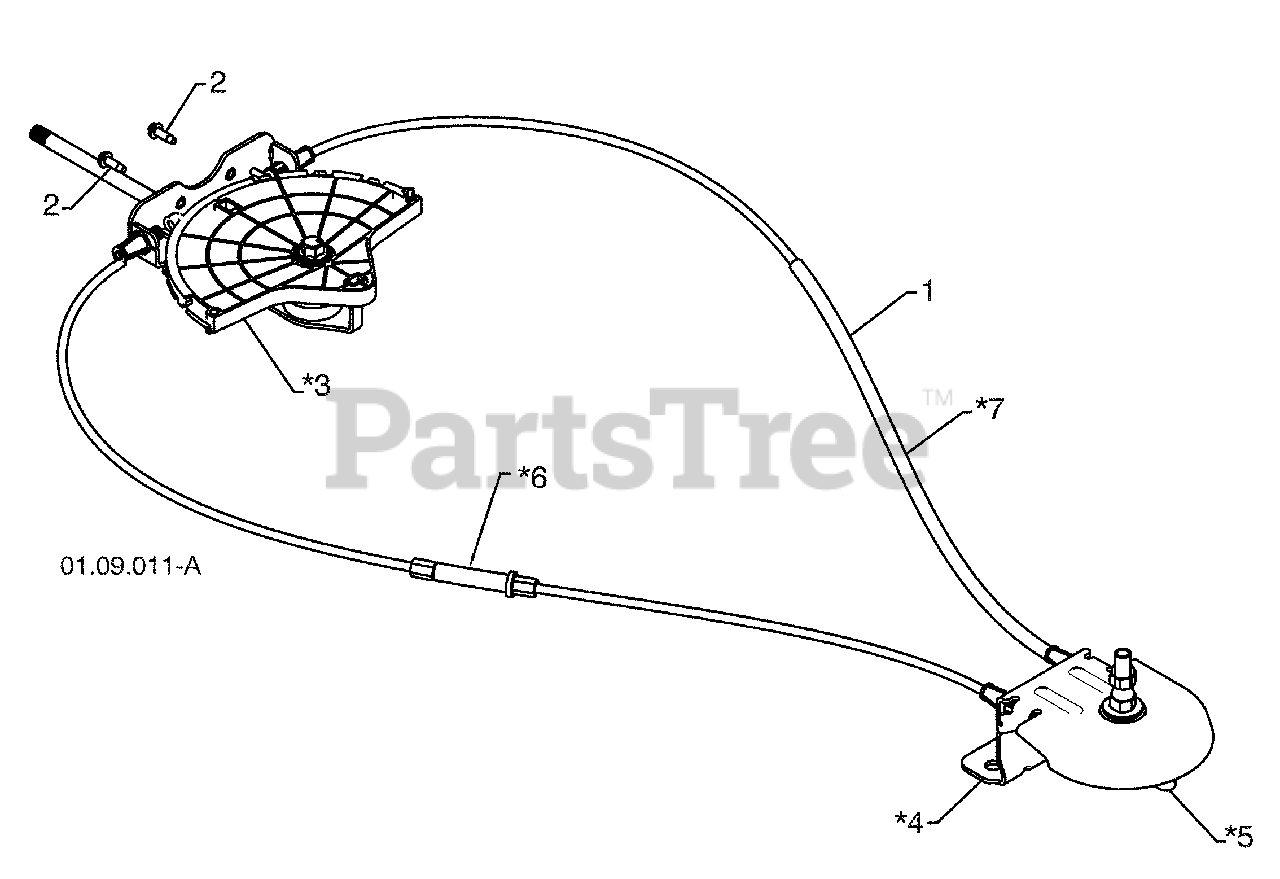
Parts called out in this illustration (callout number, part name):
1	LEVER/CABLE ROTATOR ASSEMBLY
2	SCREW 10-24 X .625
3	ROTATOR HEAD
4	ROTATOR PIVOT BRACKET
5	PULLEY PIVOT
6	CABLE ASSEMBLY ADJUSTABLE GRAY
7	CABLE ASSEMBLY HEAT SHIELD GRAY
